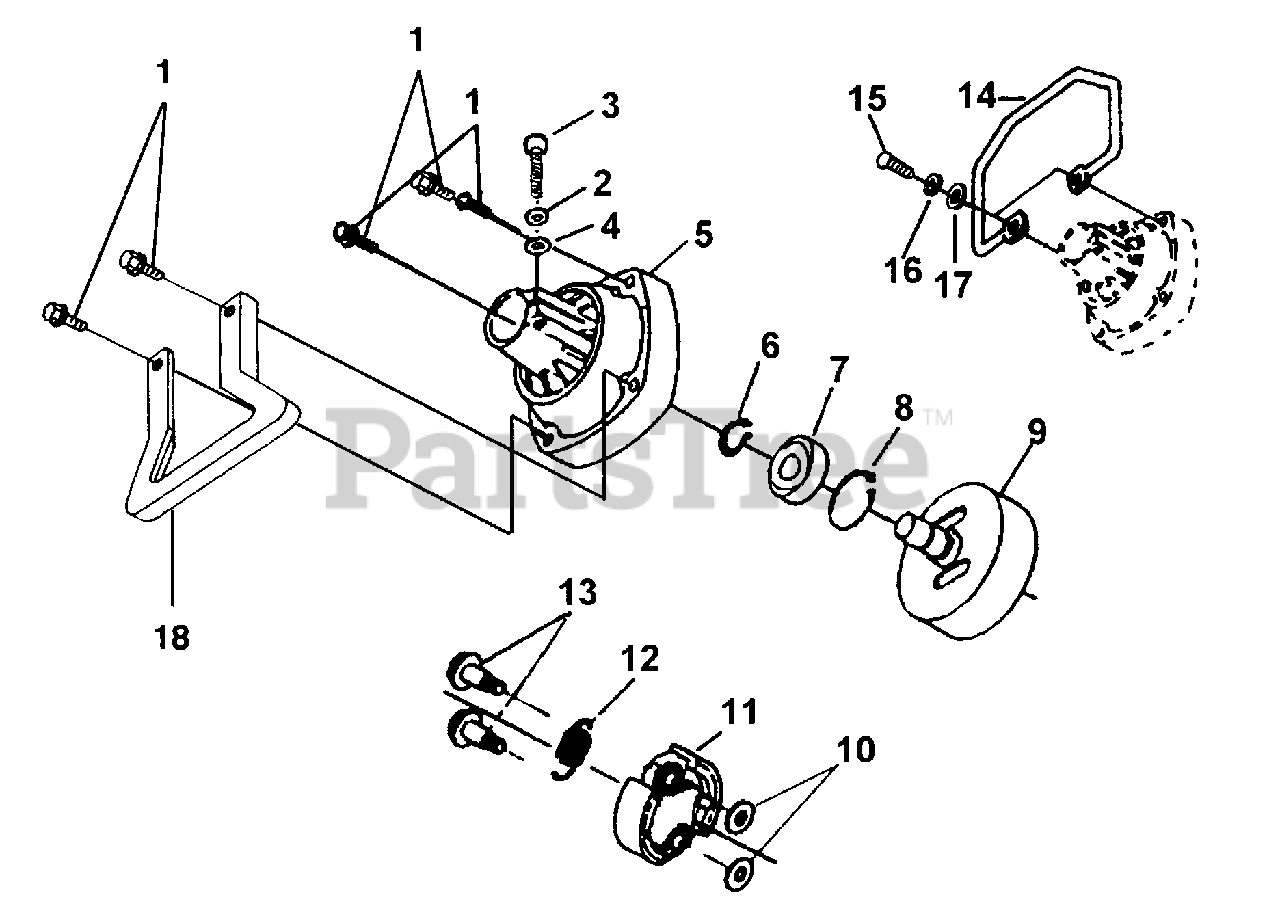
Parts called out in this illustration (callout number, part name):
1	BOLT & WASHER
3	SCREW
5	CLUTCH CASE
6	SNAP RING
8	SNAP RING
9	CLUTCH DRUM
11	CLUTCH SHOE KIT
12	CLUTCH SPRING
13	BOLT
14	GUARD, HEAT (4000j)
15	BOLT (4000j)
16	WASHER, LOCK (4000j)
17	WASHER, FLAT (4000j)
